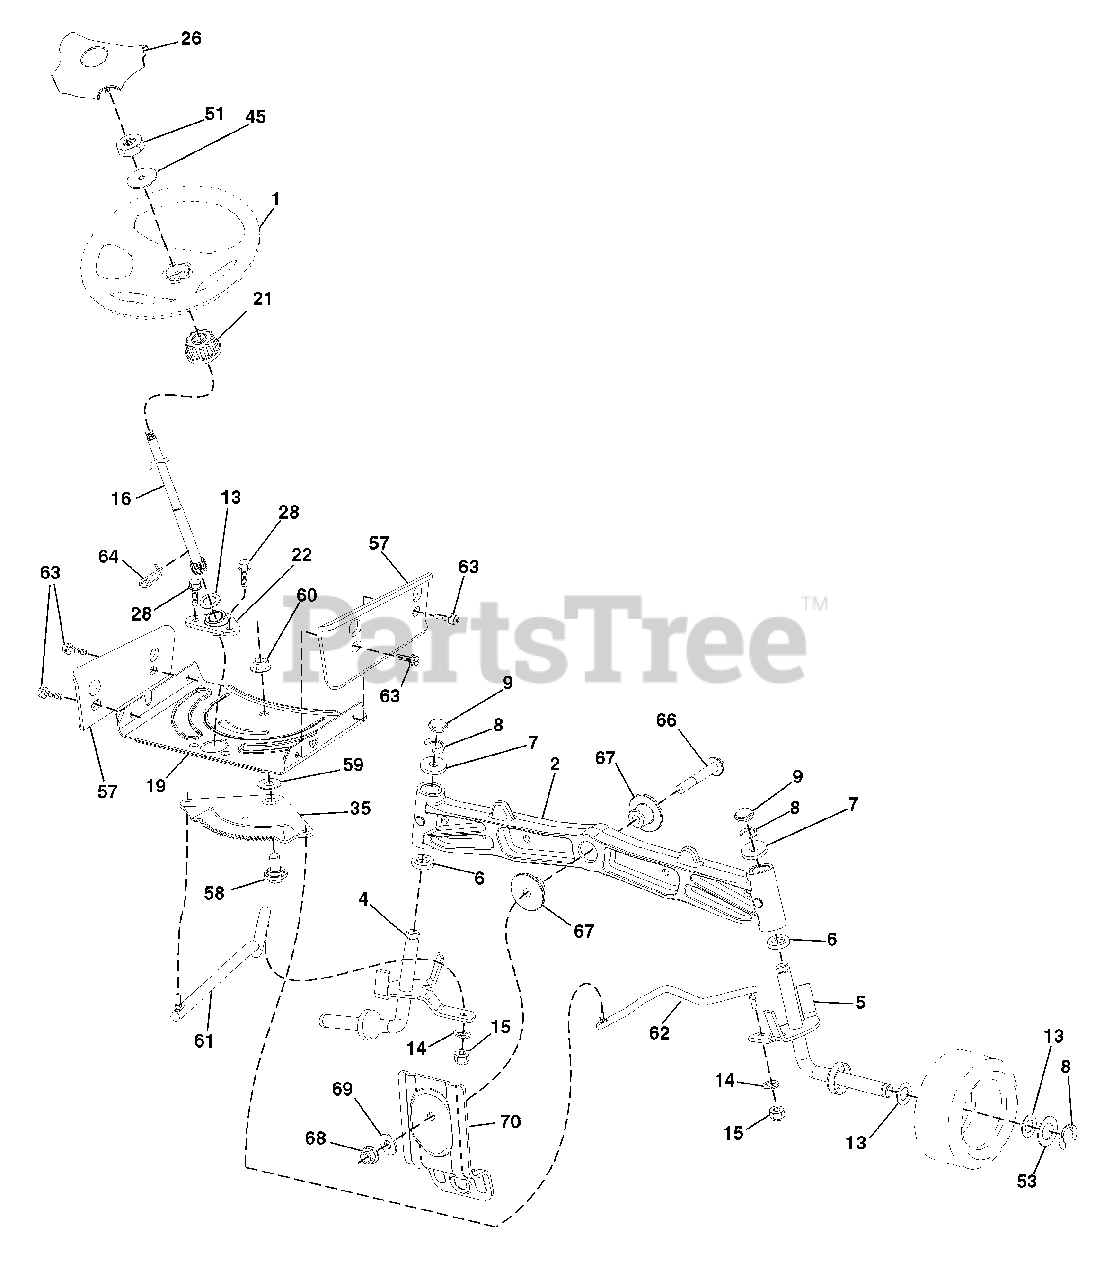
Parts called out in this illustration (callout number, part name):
1	Wheel, Steering
2	Axle Asm., Front
4	Spindle Asm., LH
5	Spindle Asm., RH
6	Bearing, Race Thrust Harden
7	Washer 25/32 x 1-5/8 x 16 Ga.
8	Ring, Clip #T5304-75
9	Cap, Spindle
13	Washer 25/32 x 1-1/4 x 16 Ga.
14	Washer, Lock Hvy Hlcl Spr 3/8
15	Nut, Crown Lock 3/8-24 unf
16	Shaft Steering
19	Plate Steering
21	Adapter, Wheel Steering
22	Bushing, Strg. Blk
26	Insert, Wheel Steering
28	Screw 3/8-16 x 3/4
35	Gear, Sector Plate
45	Washer 9/16 x 2-3/8 x 12 Ga.
51	Nut Hex Jam Toplock 1/2-20 unf
53	Washer Hardened .793 x 1.637 x .060
57	Bracket Upstop
58	Bolt Shoulder Sector Pivot CFM
59	Washer Thrust Sector Steering
60	Nut Flange Lock 5/8-11
61	Draglink, LH
62	Draglink, RH
63	Screw 5/16-18 x 3/4
64	Retainer Clip Spring Steering
66	Bolt Hex Fghd 7/16-14 x 3 Serr
67	Bushing PM Front Axle
68	Nut Lock Flange 7/16-14 Gr. 5
69	Washer 1.5 x .505 x .118
70	Bracket Deck Susp. Front
